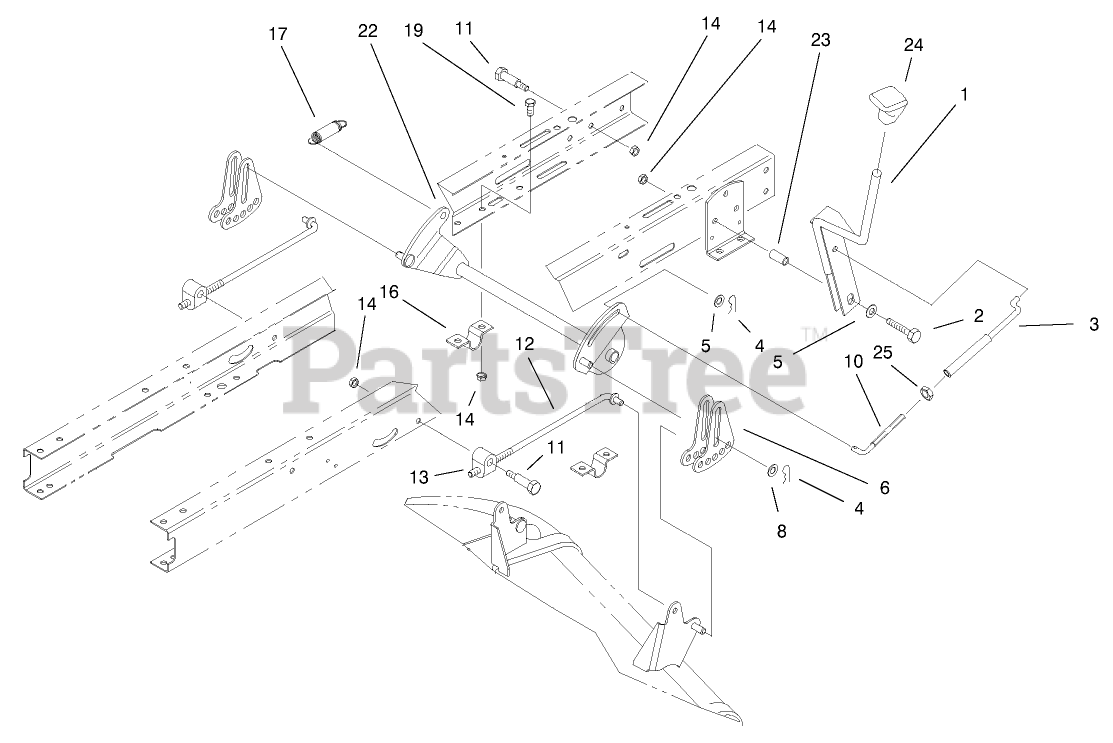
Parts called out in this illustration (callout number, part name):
2	SCREW-HH
3	HOC LINKAGE (WELDMENT)
5	WASHER-FLAT
6	LINK-ADJUSTING, HOC
8	WASHER-HARDENED
10	LINKAGE-HOC
11	SCREW-SHOULDER, HH
12	ROD-HANGER, REAR
13	TRUNNION-HOC
14	NUT-LOCK, NI
16	CLAMP-PIVOT, HOC
17	SPRING-EXTENSION
19	SCREW-HH
22	HOC PIVOT ASM (BLACK)
23	SPACER
24	KNOB-SHIFT
25	NUT-JAM
